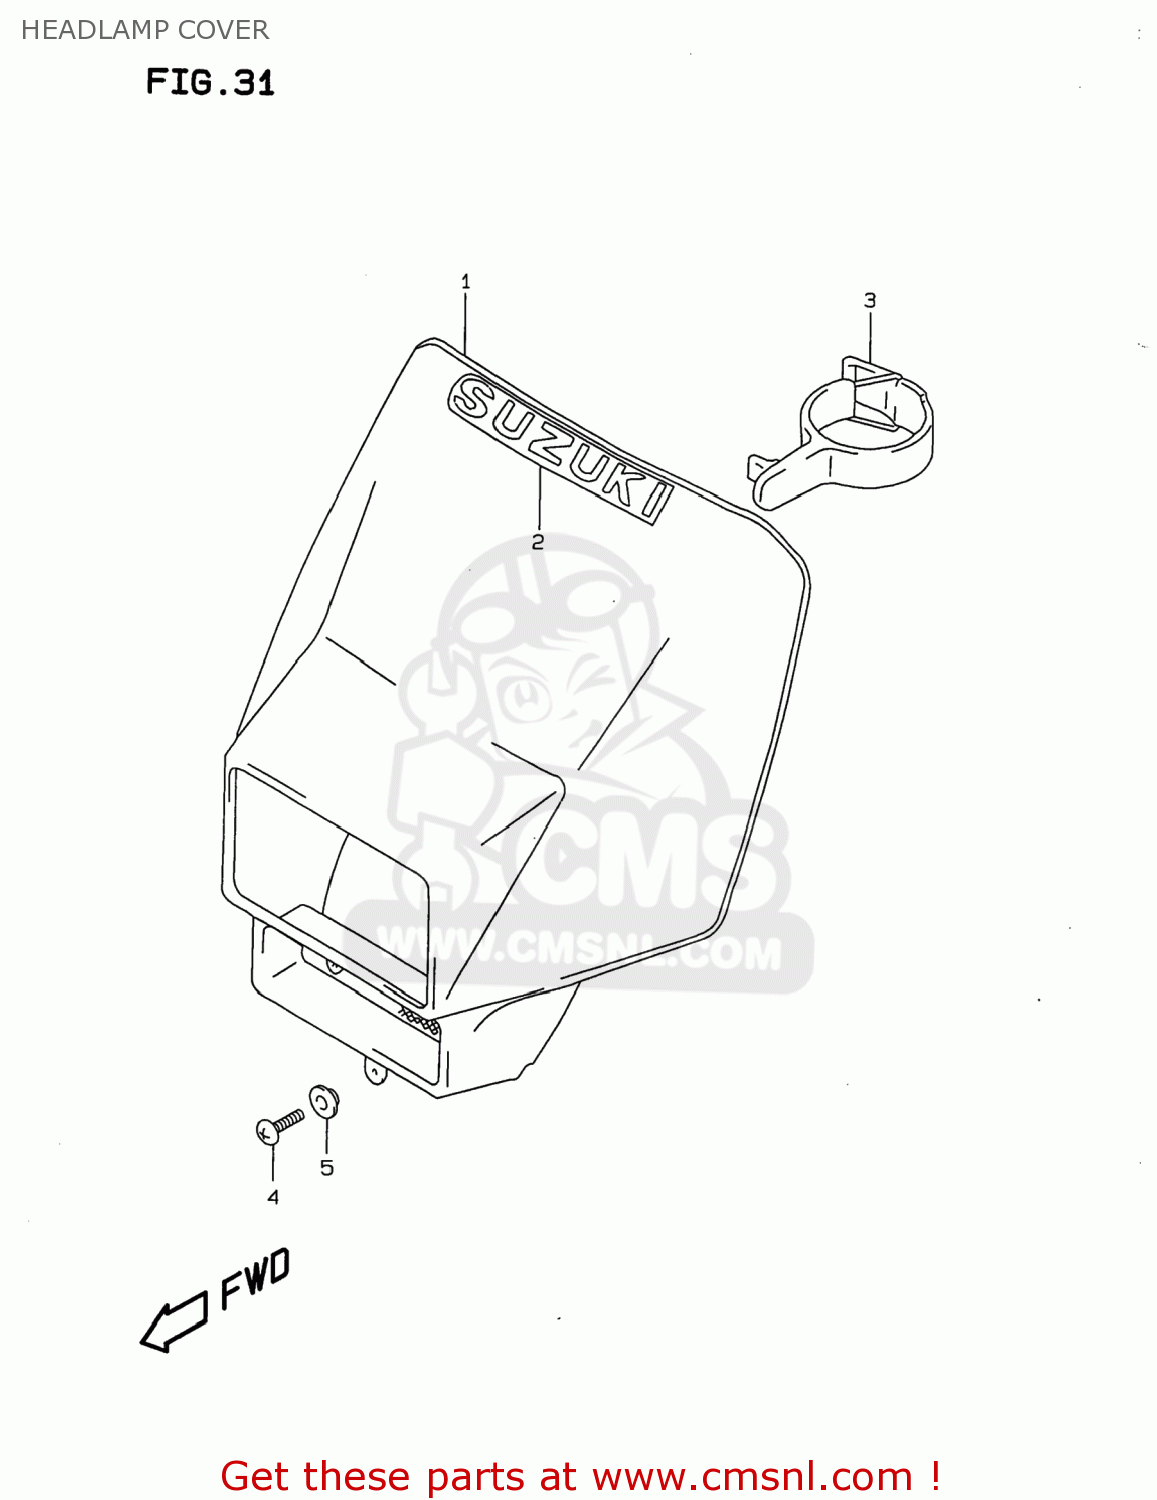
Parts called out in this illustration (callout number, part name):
1	COVER,HEADLAMP
2	EMBLEM
3	BAND,HEADLAMP COVER
4	SCREW(5X12)
5	WASHER
